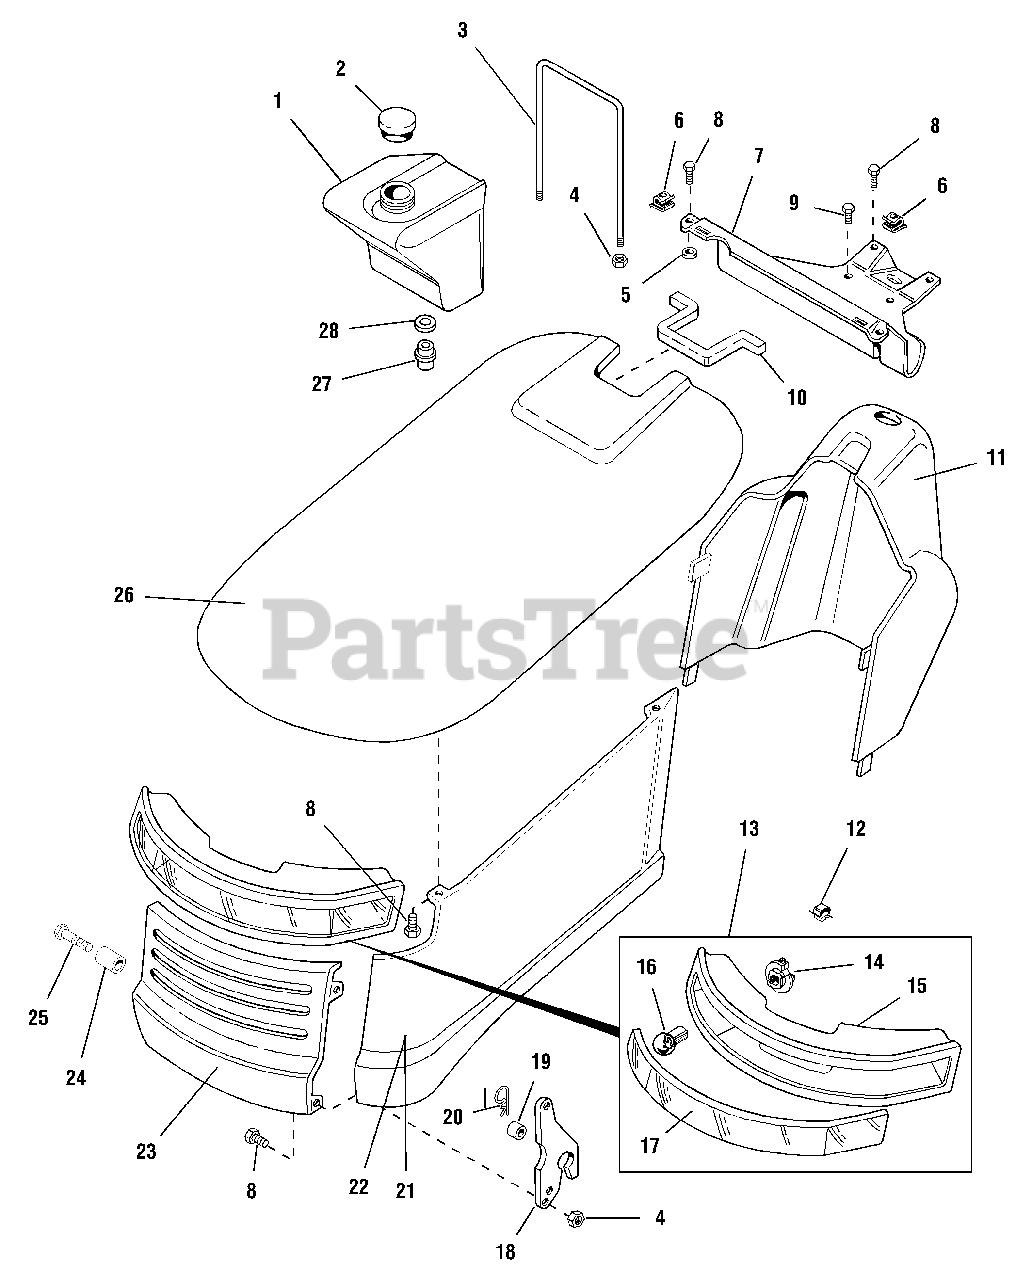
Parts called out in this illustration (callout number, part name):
1	FUEL TANK
2	CAP, Fuel Tank
4	NUT, Hex, Nylon Lock, 1/4-20
5	WASHER, 1/4
6	PAL NUT, 1/4-20
8	SCREW, Hex, Whizlock, 1/4-20 x 5/8
9	SCREW, Taptite, 1/4-20 x 1/2
10	GROMMET, Strip
13	LIGHT BAR ASSY.
14	SOCKET, Bulb
16	BULB, #1156
18	HINGE, Hood
19	SPACER, Hood
20	CLIP, Hairpin
21	PANEL, Side, LH, Orange
21	PANEL, Side, LH, Red
22	PANEL, Side, RH, Orange
22	PANEL, Side, RH, Red
23	GRILLE, Orange
23	GRILLE, Red
25	CAPSCREW, Hex, 1/4-20 x 1-1/2
26	HOOD, Orange
27	FITTING, Fuel
28	GROMMET, Fuel Fitting
